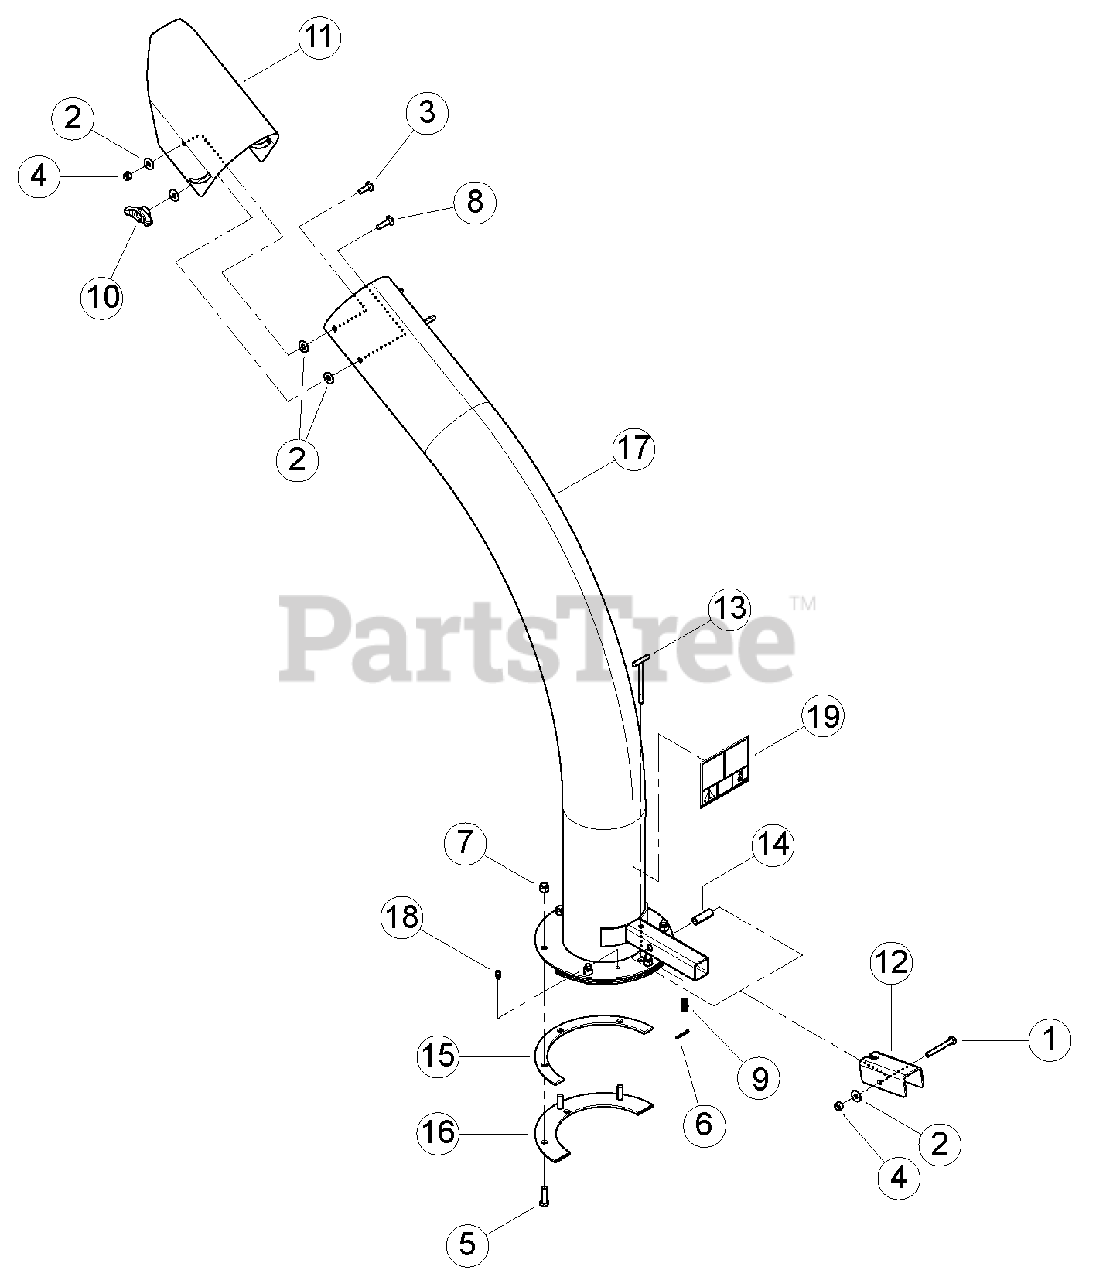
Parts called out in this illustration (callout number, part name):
1	BOLT, 5/16 X 2-1/2 HEX HD GR5 ZP
2	WASHER, 5/16 FLAT ZP
3	BOLT, 5/16 X 1 CRG GR5 ZP
4	NUT, 5/16 NE NYLOCK ZP
5	BOLT, 3/8 X 1-1/4 HEX HD GR5 ZP
6	PIN, 1/8 X 1.00 COTTER ZP
7	NUT, 3/8 NE NYLOCK ZP
8	BOLT, 5/16 X 1-1/4 CRG GR5 ZP
9	SPRING, LOCK COMPRESSION (WAS 16556, REMOVED)
10	KNOB, 5/16-18 UNC TEE W/LOCKING INSERT
11	DEFLECTOR, BLOWER-VAC DISCHARGE
12	LEVER, DISCHARGE LOCK (WAS 71252, REMOVED)
14	TUBE, DISCHARGE LOCK PIVOT (WAS 71256, REMOVED)
15	SPACER, DISCHARGE PIVOT
16	RING, DISCHARGE CLAMP
17	ASSEMBLY, 6 INCH DISCHARGE, SERVICE PART
18	FITTING, 1/4 SELF-TAP GREASE
19	DECAL, DISCHARGE DEBRIS & LOCK
